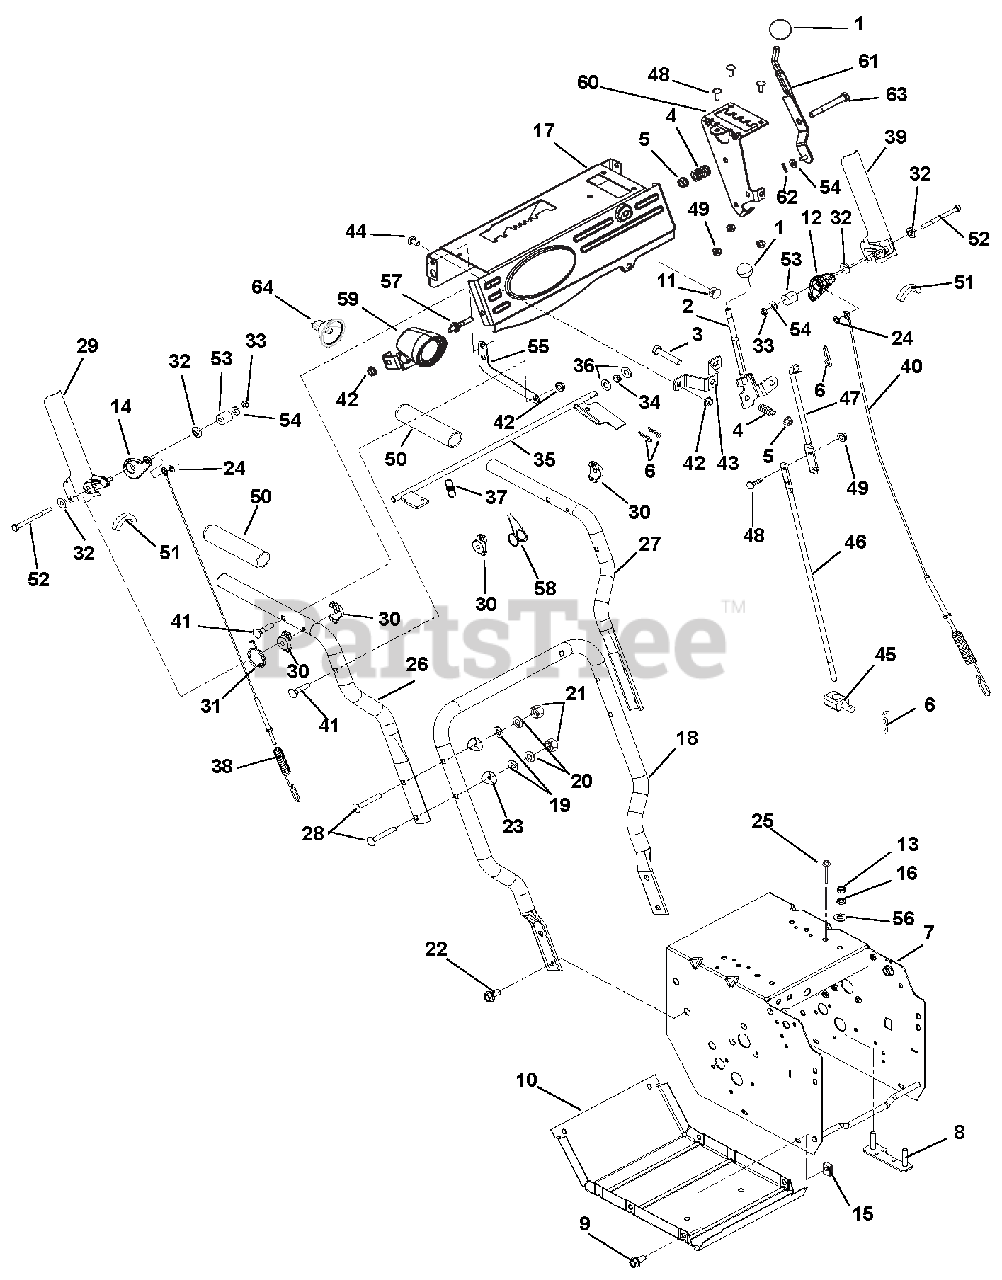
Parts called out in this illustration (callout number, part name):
1	KNOB,BALL -BLACK 1.47" .375-16
2	WMT, SHIFT LEVER
3	@BLT-HEX .38-16X2.00 GR5 YWZC
4	SG-COMP .125X.781X1.250
5	@NUT-LK-TOP-FLG .38-16 YWZC
6	PIN-HAIR INT .08X.18X1.18 YWZC
7	FRAME, 920/921
8	STRAP, ENGINE BOLT-WELDMENT
9	BLT-HEX .25-20X.75 HWH YZ GR5
10	COVER, BOTTOM
11	HOLE PLUG, PLASTIC .44 HOLE
12	CAM, INTERLOCK - LH
13	@NUT-HEX .31-18 YWZC
14	CAM, INTERLOCK - RH
15	NUT-RTNR .25-20X.56
16	WSHR-LK .312X.097 HVY YWZC
17	CONTROL PANEL W/DECAL
17	CONTROL PANEL W/DECAL, REMOTE
18	HANDLEBAR, LOWER (COMPACT)
19	@WSHR-FL-STL.38X.875X.083 YWZC
20	WSHR-LK .312X.097 HVY YWZC
21	@NUT-LK-NYL .312-18 YWZC
22	BLT-SERHFWH .38-16X.75 YWZC
23	SPACER, HANDLEBAR
24	RG-RTNG-EXT .250X.010
25	RVT-POP .187 YZ
26	HANDLEBAR, UPPER - RH COMP/DEL
27	HANDLEBAR, UPPER - LH COMP/DEL
28	@BLT-RDHDSQNK .31-18X2.25 G5YZ
29	PADDLE, CLUTCH - RH COMPACT
30	SPACER, HANDLEBAR
31	SPRING, TORSION
32	BSHG, FLG .266X.42X.150 PM
33	NUT-JAM-NYL .250-20 W/INSERTYZ
34	BUSHING, POLYLINER-.38 SNAPIN
35	WELDMENT, INTERLOCK SHAFT
36	@WSHR-FL-STL.406X.812X.065 YWZ
37	SPRING, EXTENSION
38	CABLE, ATTACHMENT, COMPACT
39	PADDLE, CLUTCH - LH COMPACT
40	CABLE, TRACTION - COMPACT
41	BLT-RDHDXLSQNK .31-18X1.5 G5YZ
42	@NUT-LK-TOP-FLG .31-18 YWZC
43	BRKT, SHIFT MOUNT
44	@BLT-RHDSSQNK .31-18X1.00 G5YZ
45	PIVOT,SHIFT ROD .375-16(TRUNN)
46	ROD, SHIFT - LOWER
47	ROD, SHIFT - UPPER
48	@BLT-RDHDSQNK .25-20X.75 G5YZ
49	@NUT-LK-TOP-FLG .25-20 YWZC
50	HANDLE GRIP
51	EDGING, CLUTCH PADDLE - 2.00"
52	@BLT-HEX .25-20X3.25 YWZC
53	BSHG, SLV .266 X .750 X .750
54	@WSHR-FL-STL.281X.62X.065 YWZC
55	STRAP, SUPPORT - DASH PANEL
56	@WSHR-FL-STL.344X.688X.065YWZC
57	STUD,.31-18X.5,.318-18X1.5
58	SPRING, TORSION, DUAL COIL
59	HEAD LIGHT ASSEMBLY
60	WMT, DEFLECTOR DETENT BRACKET
61	CONTROL, DEFLECTOR - COMPACT
62	PIN-HAIR INT .06X.18X.77
63	@BLT-HEX .38-16X3.25 GR5 YWZC
64	BULB, MR16 20W FLOOD
